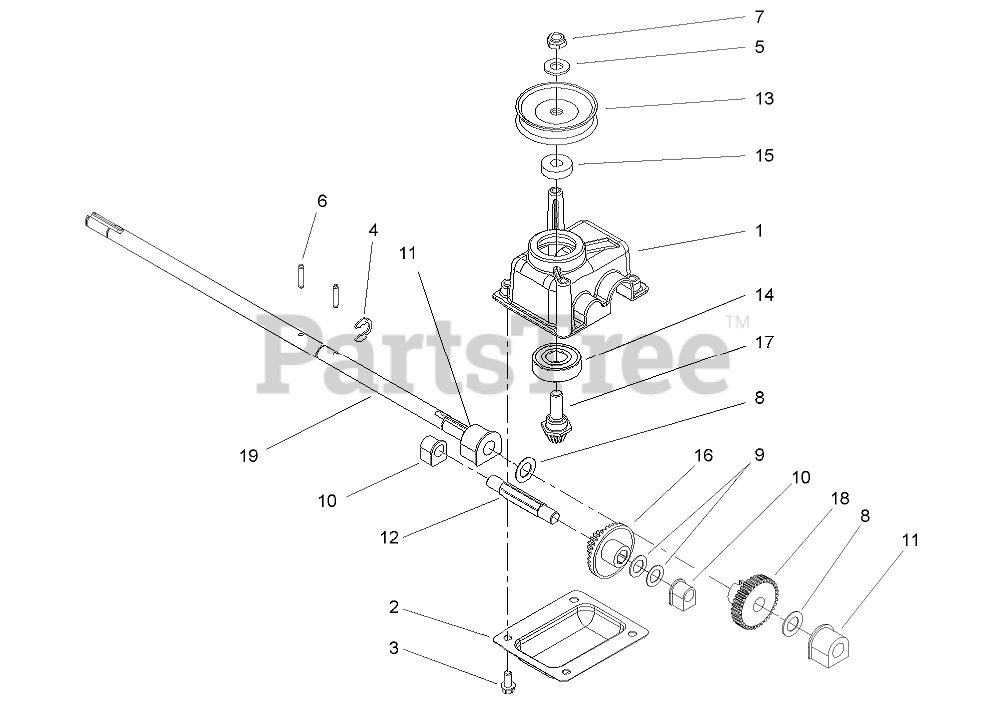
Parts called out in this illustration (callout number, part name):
1	CASE-GEAR
2	COVER-CASE, GEAR
3	SCREW-HWH
4	RING-RETAINING
5	WASHER-FLAT
6	PIN-GROOVE
7	NUT-HEX
8	WASHER-PLAIN
9	WASHER-THRUST
10	BUSHING
11	BUSHING
12	SHAFT-INTERMEDIATE
13	PULLEY-HALF
14	BEARING-BALL
15	SPACER
16	GEAR-15T SPUR, 37T BEVEL
17	GEAR-PINION, BEVEL
19	SHAFT-OUTPUT
